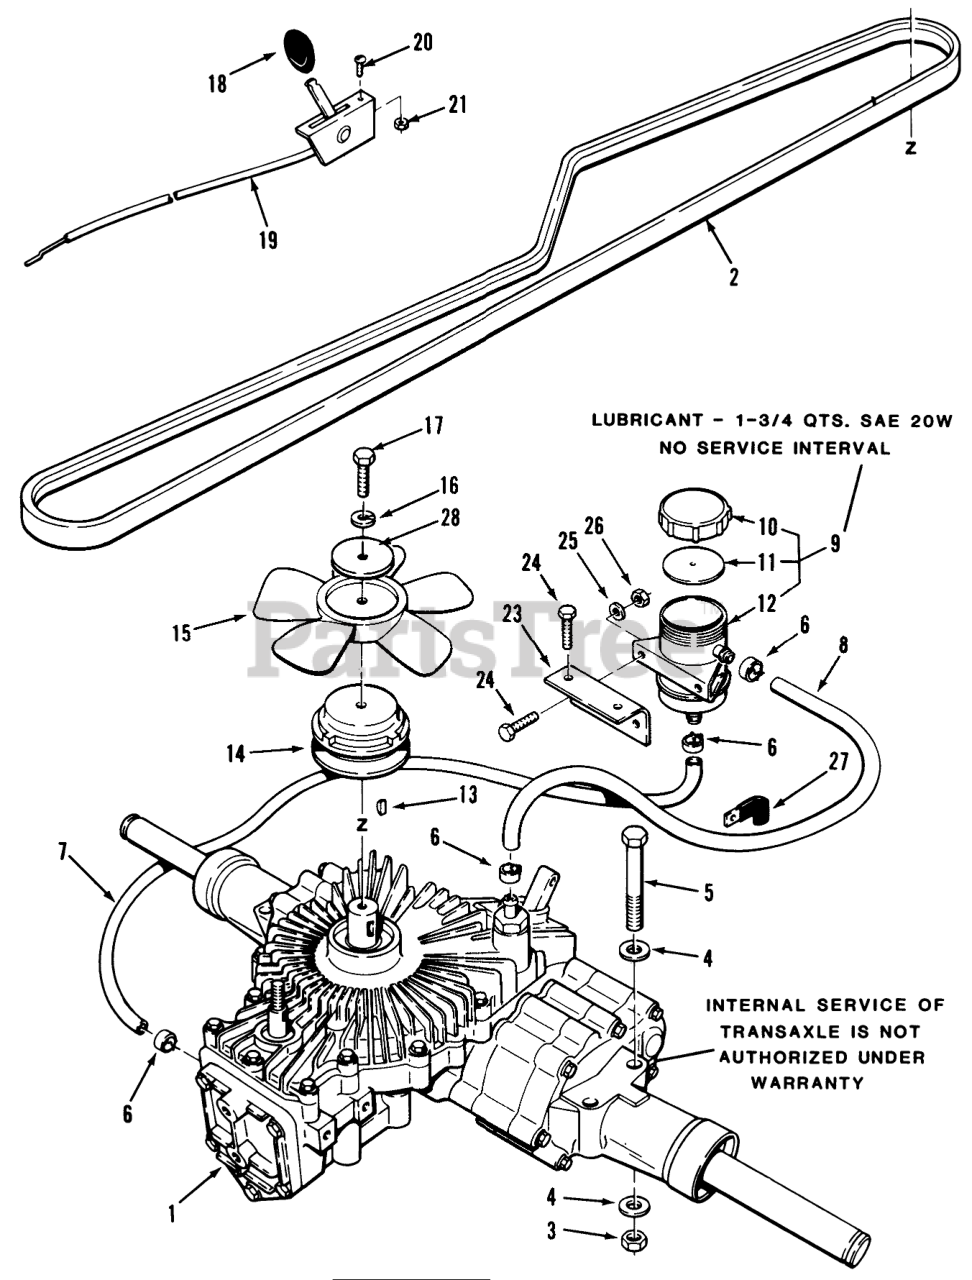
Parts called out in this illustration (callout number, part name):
1	TRANSMISSION 750-019
2	BELT V
3	Nut
4	WASHER 5/16 SAE
5	Pin-Cotter
6	CLAMP
7	S/A 9" OF 114702
8	S/A 27" OF 114702
9	Hydro Reservoir Complete (includes items 10, 11 & 12)
10	COVER
11	COVER GASKET
12	RESERVOIR
13	HARD HI PRO KEY
14	PULLEY-HYDRO
15	BLADE-FAN
16	Washer
17	Bolt
18	KNOB-THROTTLE
19	CABLE-PUSH VALVE
20	Screw #10-24 x 1/2
21	Nut
23	BRKT-RESERVOIR MT R
24	Bolt
26	Nut
27	CLIP
28	WASHER
